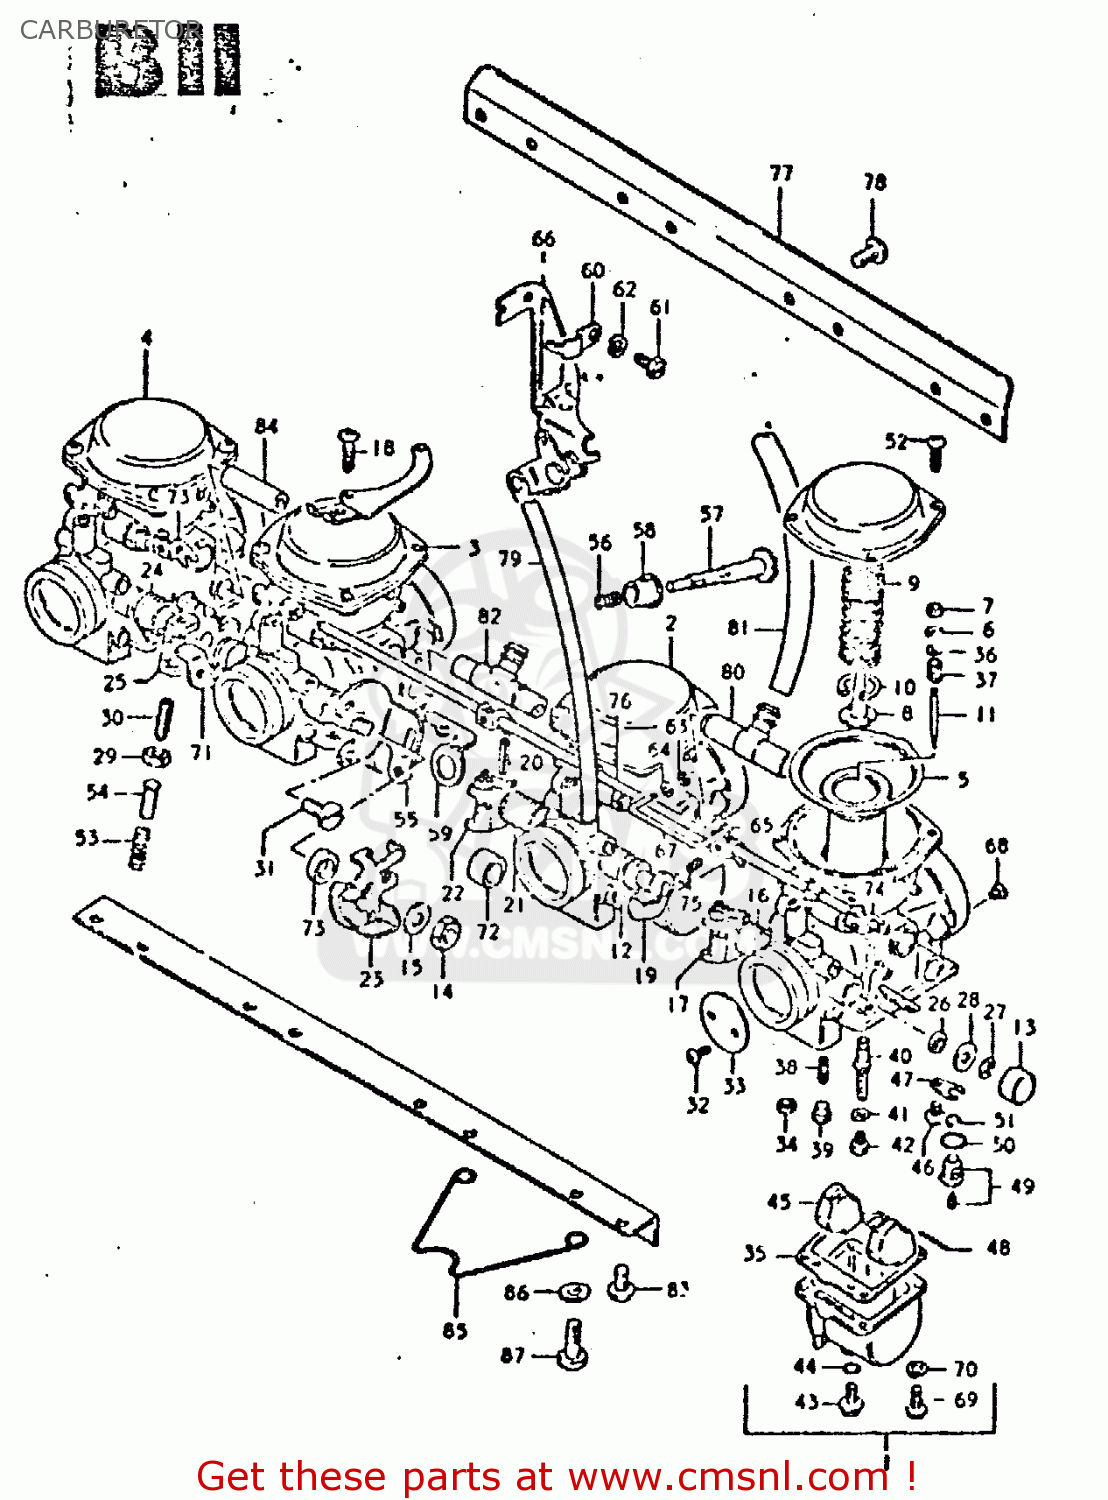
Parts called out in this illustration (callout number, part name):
1	CARBURETOR, NO.1
2	CARBURETOR, NO.2
3	CARBURETOR, NO.3
4	CARBURETOR, NO.4
5	DIAPHRAGM
6	CLIP,NEEDLE
7	RING
8	HOLDER,GUIDE
9	SPRING
10	E RING
11	NEEDLE,JET
12	GASKET
13	CAP
14	NUT
15	WASHER
16	SPRING,THROTTLE SHAFT
17	SHAFT,THROTTLE
18	SCREW
19	SHAFT,THROTTLE
20	PIN,THROTTLE SHAFT
21	SPRING,THROTTLE SHAFT
22	LEVER,THROTTLE SHAFT
23	LEVER ASSEMBLY,THROTTLE
24	SPRING,THROTTLE SHAFT
25	SHAFT,THROTTLE
26	SEAL
27	E RING
28	GASKET,THROTTLE SHAFT (NAS)
29	NUT
30	SCREW
31	SCREW
32	SCREW
33	VALVE,THROTTLE (BUTTERFLY)
34	GASKET (NAS)
35	GASKET,FLOAT CHAMBER (NAS)
36	WASHER
37	SPRING
38	JET, PILOT (42.5)
39	PLUG,NEEDLE JET
40	JET,NEEDLE(Y-5)
41	WASHER,NEEDLE NOZZLE
42	JET, MAIN (112.5)
43	PLUG,DRAIN
44	GASKET (NAS)
45	FLOAT
46	SCREW
47	PLATE
48	PIN,FLOAT
49	VALVE ASSEMBLY,NEEDLE
50	O-RING,NEEDLE VALVE
51	FILTER
52	SCREW
53	SPRING,THROTTLE SCREW
54	PIN,THROTTLE LEVER
55	BRACKET,THROTTLE ADJUST
56	SPRING
57	SCREW
58	BUSH
59	BRACKET,THROTTLE ADJUST
60	BRACKET,STARTER
61	BOLT
62	LOCK WASHER
63	CAP,LEVER
64	SEAT,SPRING
65	LEVER ASSY
66	BRACKET
67	ROD,STARTER LEVER
68	JET,AIR(150)
69	SCREW
70	LOCK WASHER
71	SHAFT,THROTTLE
72	RING
73	RING
74	LEVER
75	SCREW
76	SHAFT,STARTER
77	BRACKET
78	SCREW
79	HOSE
80	NIPPLE,CARBURETOR
81	HOSE
82	NIPPLE
83	SCREW 6X12
84	NIPPLE
85	CLAMP
86	WASHER
87	SCREW
